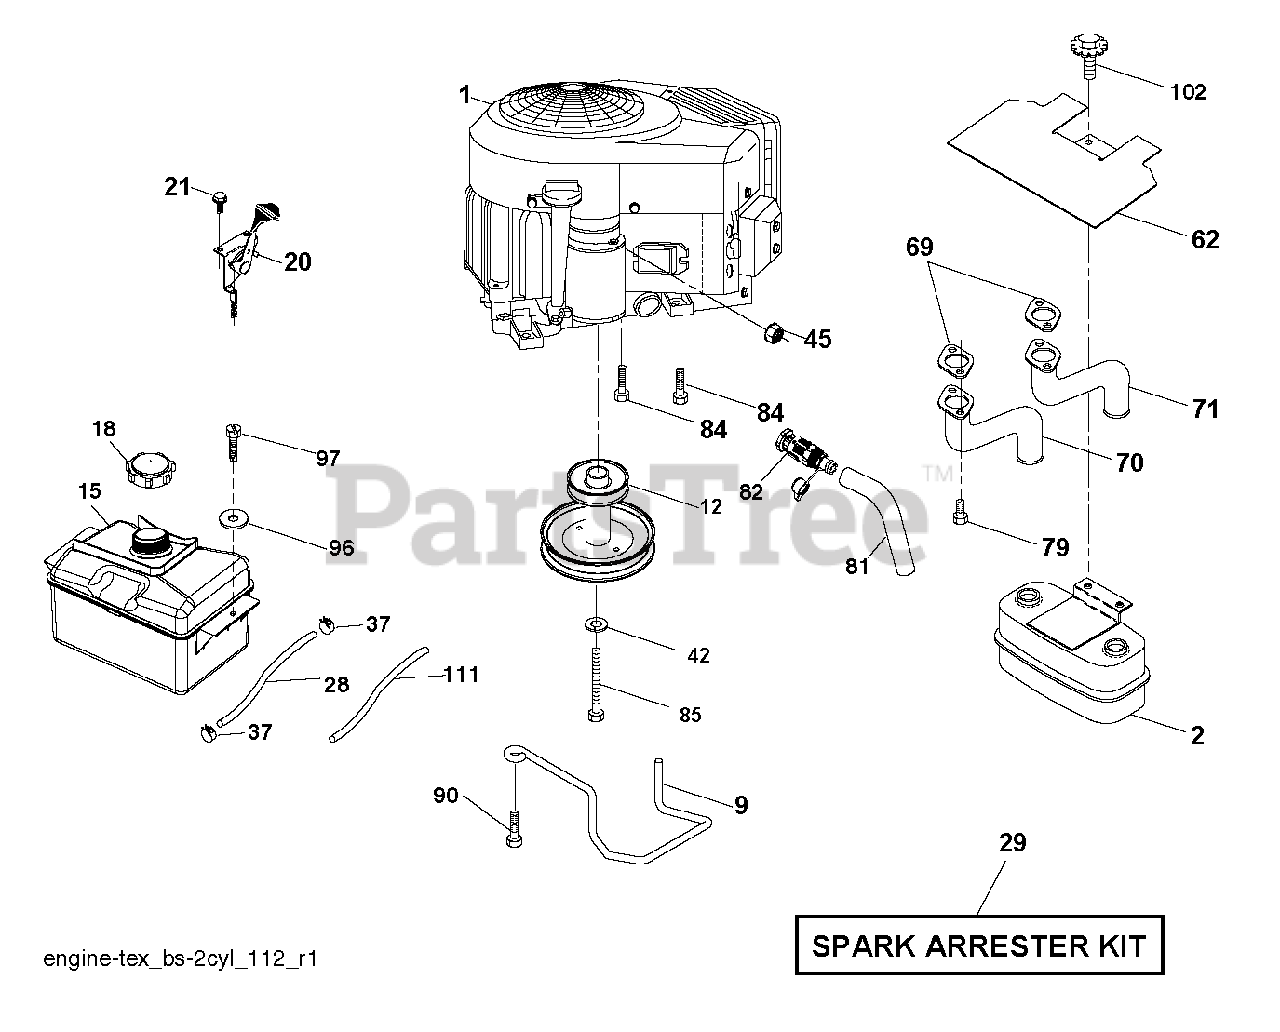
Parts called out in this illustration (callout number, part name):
2	MUFFLER.ASM.TWN.EXTNDED.DFLCTR
9	KEEPER BELT ENGINE
12	Engine Pulley
15	TANK.ASM.FRT.2.5 GAL.W/CAP.EPA
18	CAP.FUEL.2 WAY VENT
20	Throttle, Cobra 38" Readstart.Bk
21	SCREW.#10 X 0.750.BOS (2 2)
28	LINE.FUEL.20"FRONT.EMI
29	KIT.SPARK ARRESTOR(392390 B&S)
37	HOSE CLAMP
42	LOCKWASHER
45	NUT
62	SHIELD.HEAT.MUFFLER
70	EXHAUST.TUBE.LH.BS/TWIN
71	EXHAUST.TUBE.RH.B&S.TWIN.INTEK
79	SCREW.SOCKET.HEAD.5/16-18
81	TUBE, DRAIN OIL ASM.
82	VALUE.OIL.DRAIN
84	SCREW.3/8-16
85	BOLT HEX 7/16-20X4-1/4"
90	SCREW 3/8-16X1
97	SCREW HEXWSHR 1/4-20X3/4
102	SCREW
111	RP PURGE LINE
